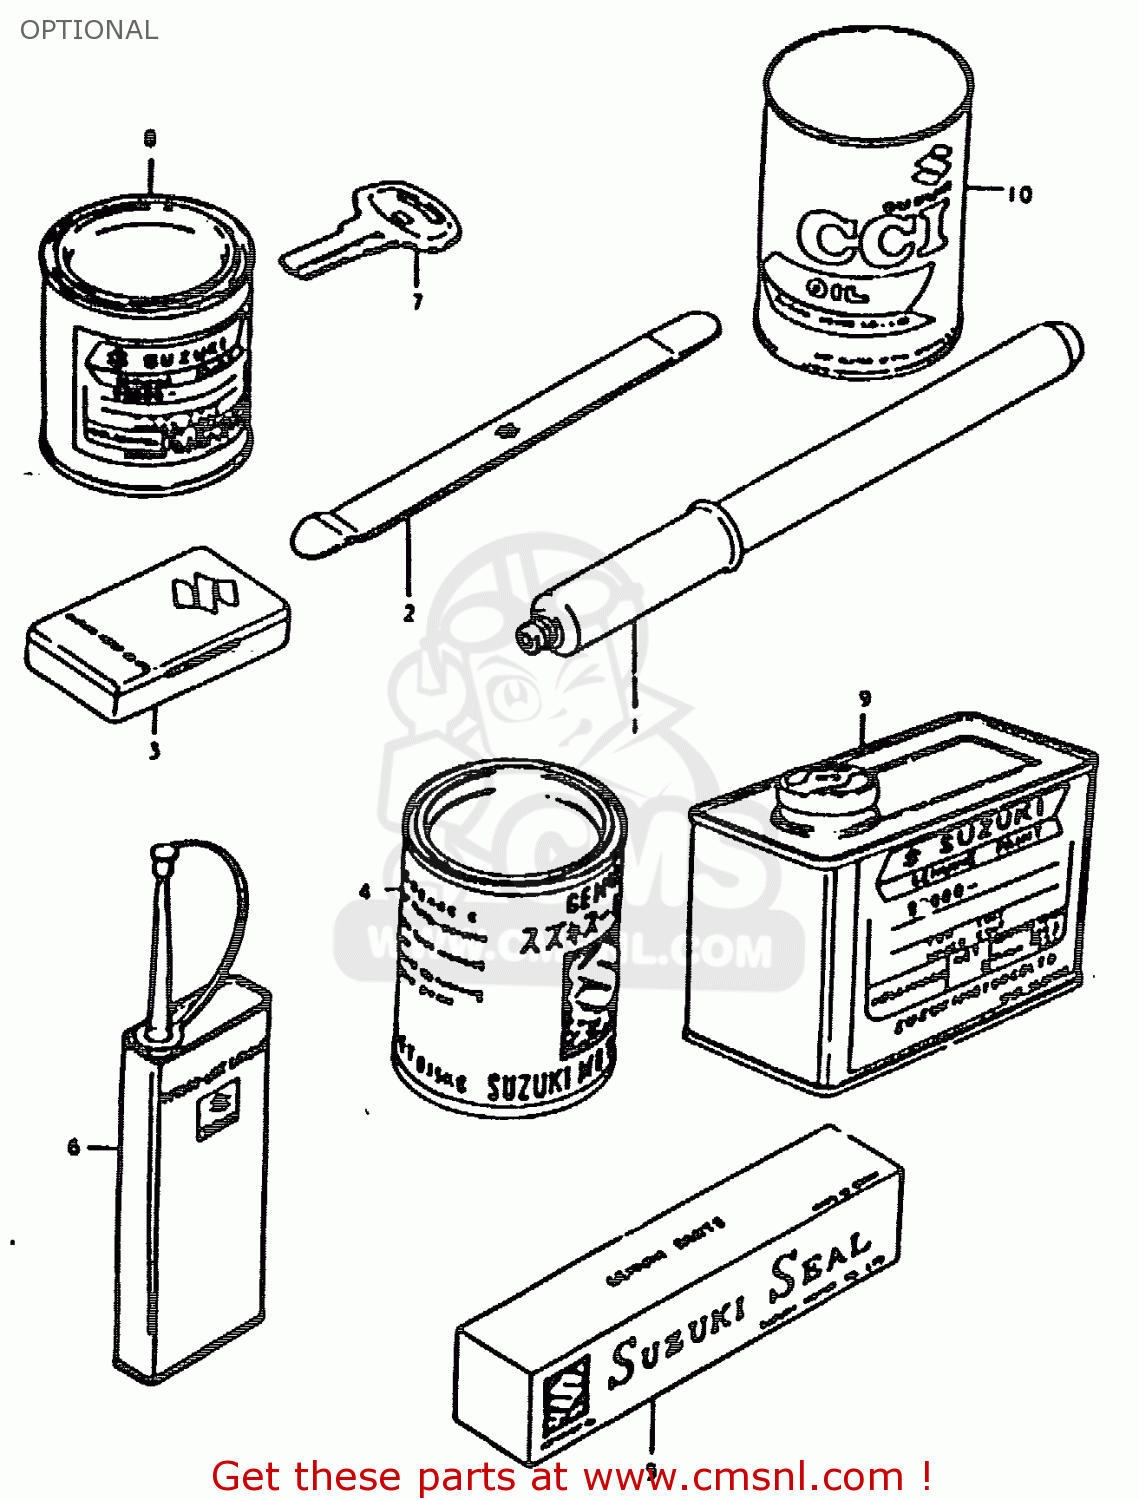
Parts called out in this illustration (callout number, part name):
1	INFLATOR, AIR
2	LEVER,TIRE
3	TUBE REPARING TOOL
4	GREASE(C)EP2 LITHIUM 150G
5	GASKET, LIQUID
6	THREAD LOCK NO.1401 CLEAR 200G
7	KEY,BLANK
8	PAINT,BLACK
9	PAINT (BLACK)
10	CCI OIL
